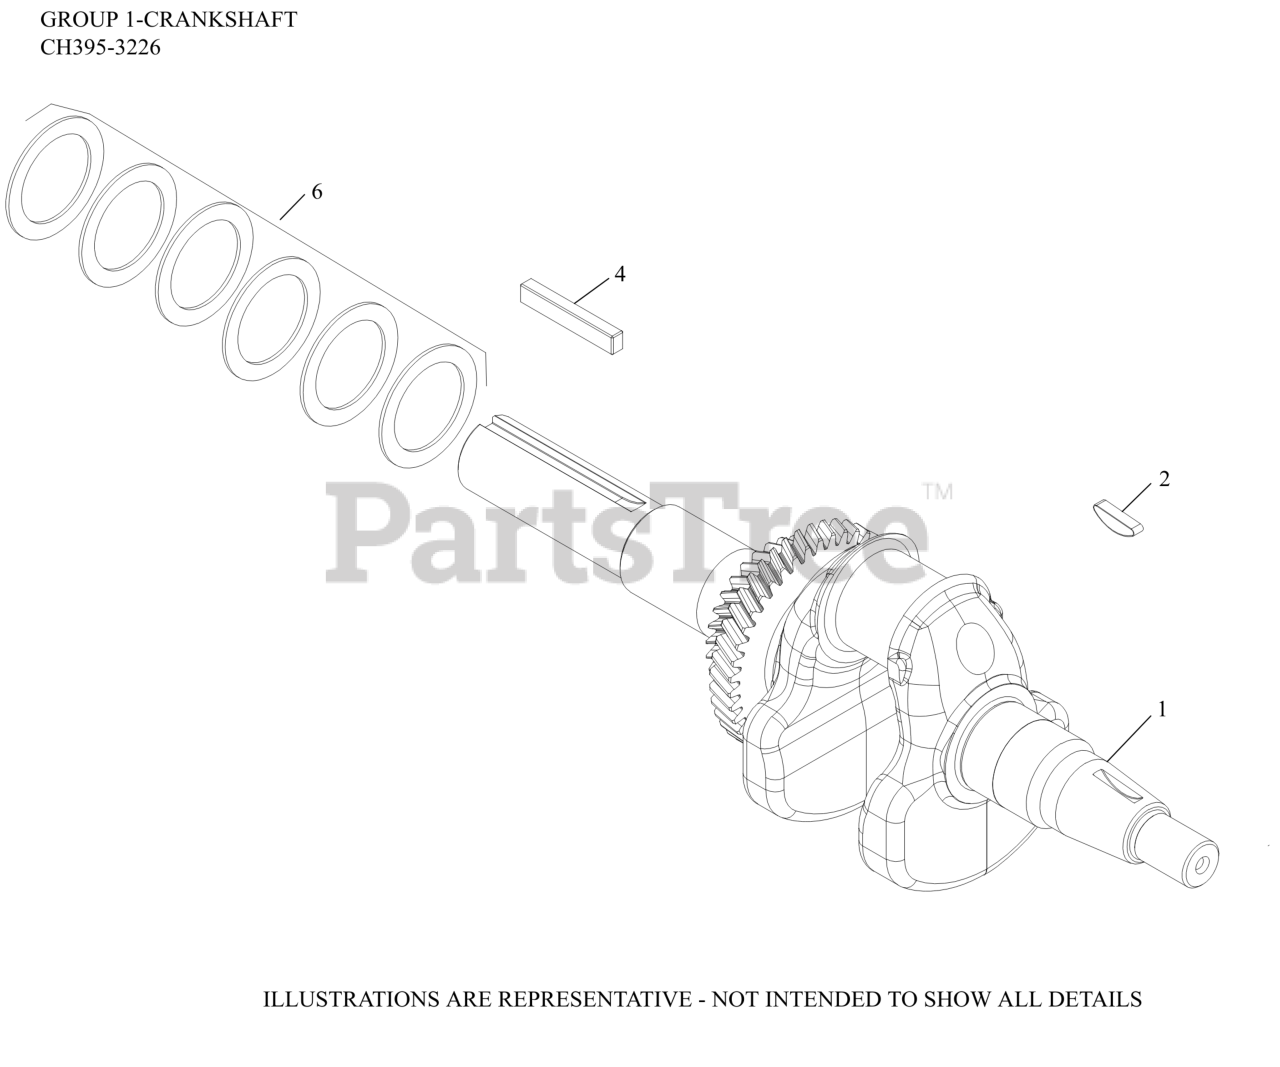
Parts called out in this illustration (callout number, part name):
1	CRANKSHAFT ASSEMBLY
2	KEY, FLYWHEEL
4	KEY, SQUARE
6	KIT, SHIMS
